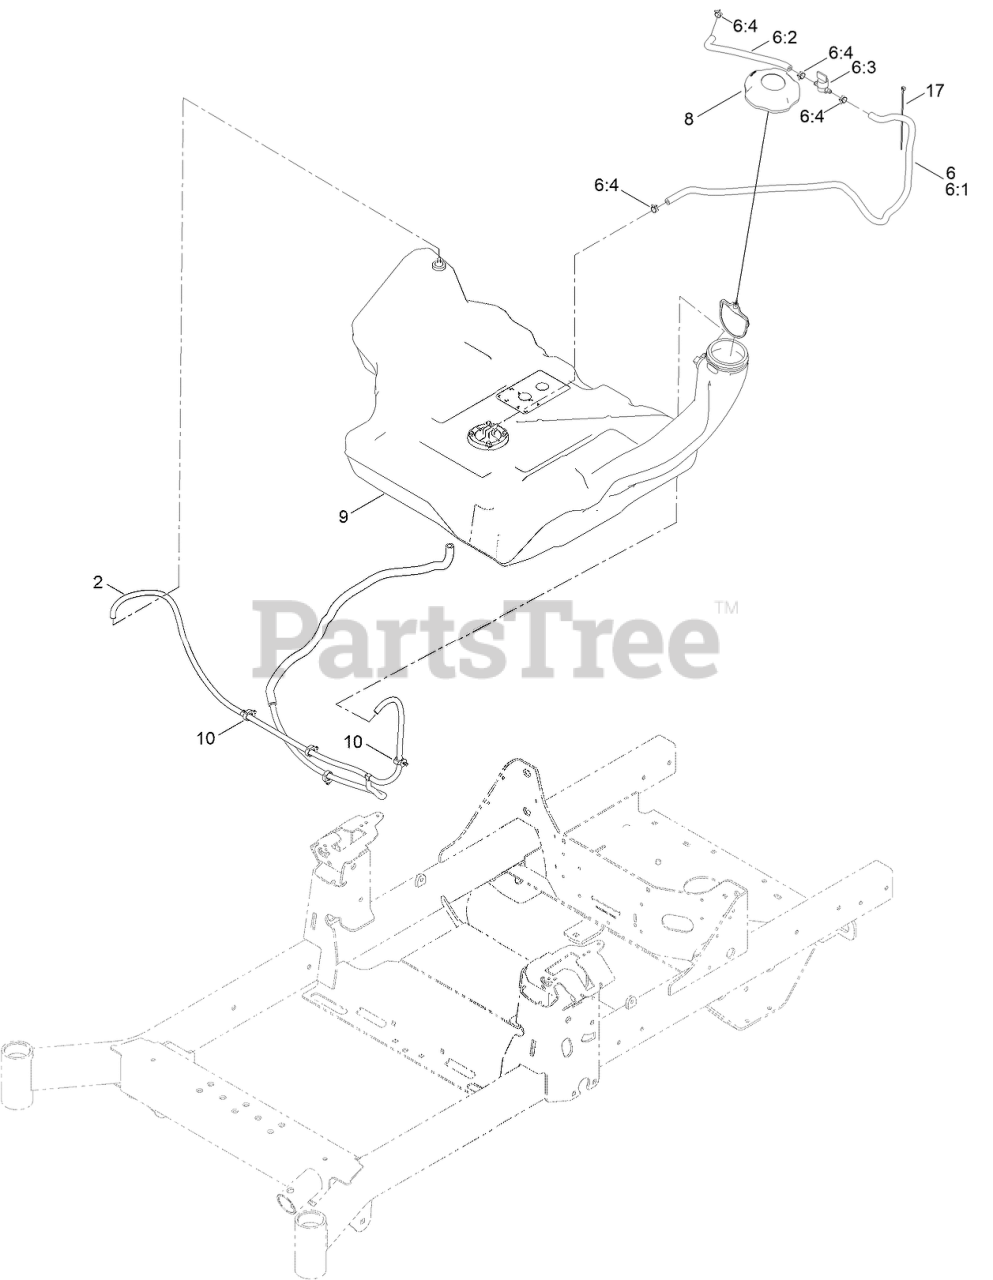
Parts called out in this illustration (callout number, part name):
2	HOSE-VENT
6	FUEL HOSE ASM
6:1	HOSE-FUEL
6:2	HOSE-FUEL
6:3	VALVE-FUEL
6:4	CLAMP-HOSE
8	CAP-FUEL, RATCHETING
9	TANK-FUEL
17	TIE-CABLE
